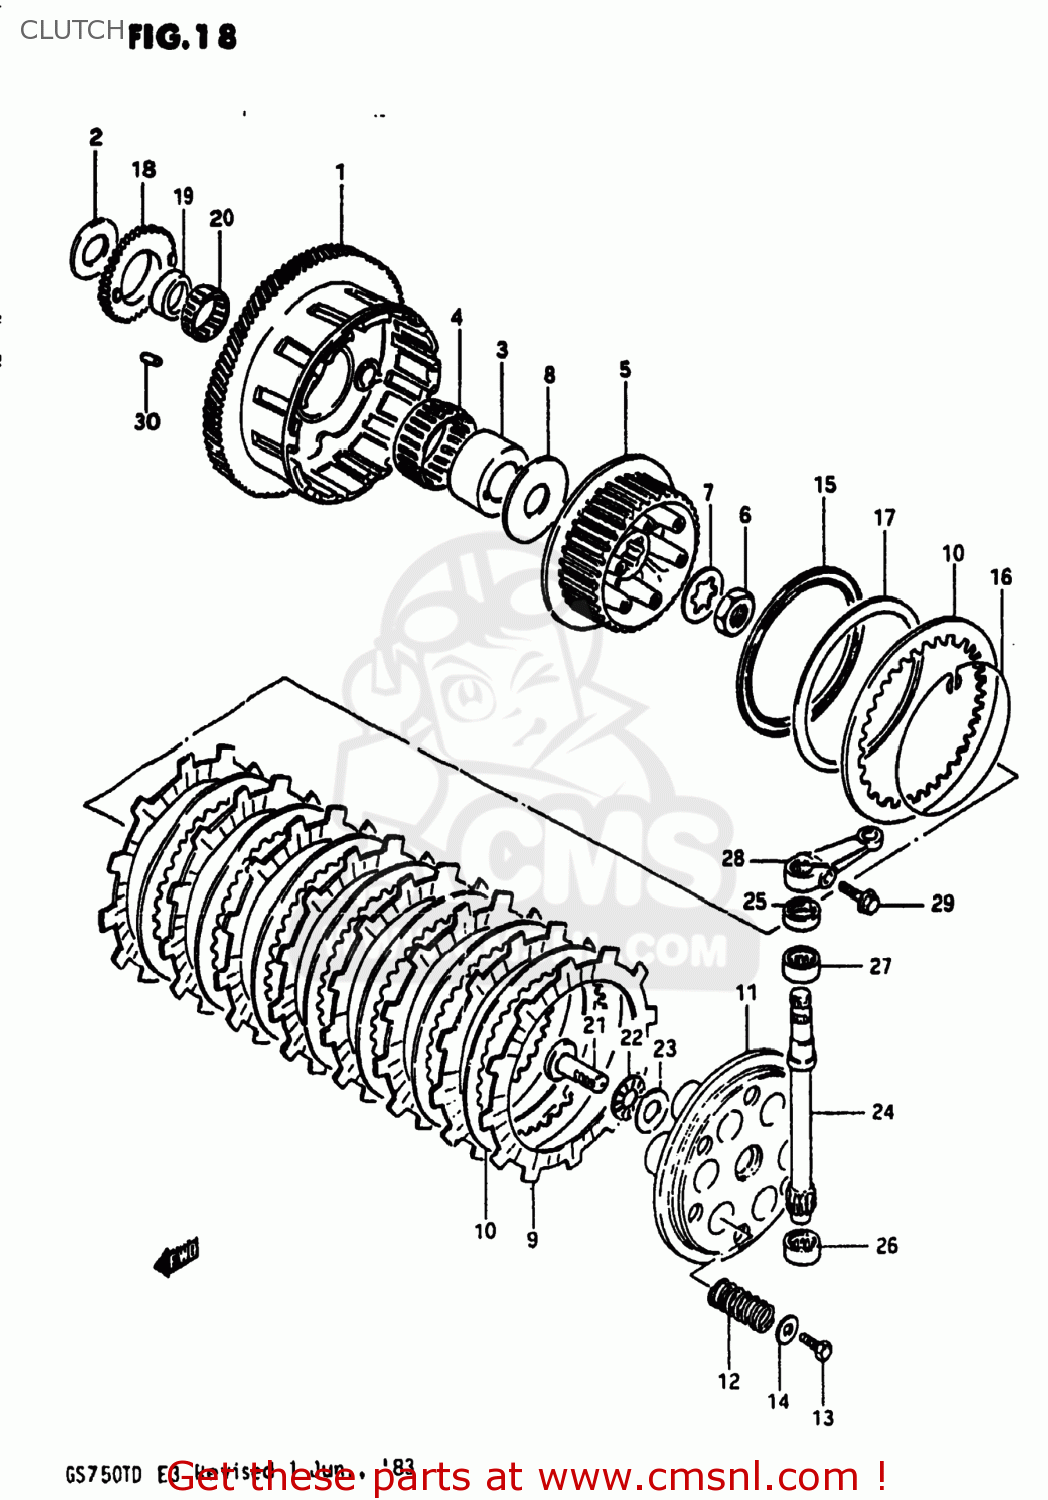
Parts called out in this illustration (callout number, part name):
1	GEAR ASSEMBLY,PRIMARY DRIVE
2	WASHER
3	SPACER
4	BEARING
5	HUB,CLUTCH SLEEVE
6	NUT
7	WASHER,LOCK
8	WASHER(25X66X3.5)
9	PLATE,CLUTCH DRIVE (MCA)
10	PLATE,CLUTCH DRIVEN(T:2.0) (NAS)
11	DISC,CLUTCH PRESSURE
12	SPRING
13	BOLT, UPPER
14	WASHER
15	SEAT,WAVE WASHER
16	RING,STOPPER
17	WASHER
18	GEAR,ENG OIL PUMP DRIVE(NT:38)
19	SPACER,OIL PUMP DRIVE GEAR
20	BEARING(36X40X10)
21	RACK,CLUTCH RELEASE
22	BEARING(15X28X2)
23	WASHER
24	PINION,CLUTCH RELEASE
25	OIL SEAL
26	BEARING(12X19X12)
27	BEARING(15X22X12)
28	ARM,CLUTCH RELEASE
29	BOLT,REAR
30	CUSHION,PRIMARY DRIVEN GEAR
